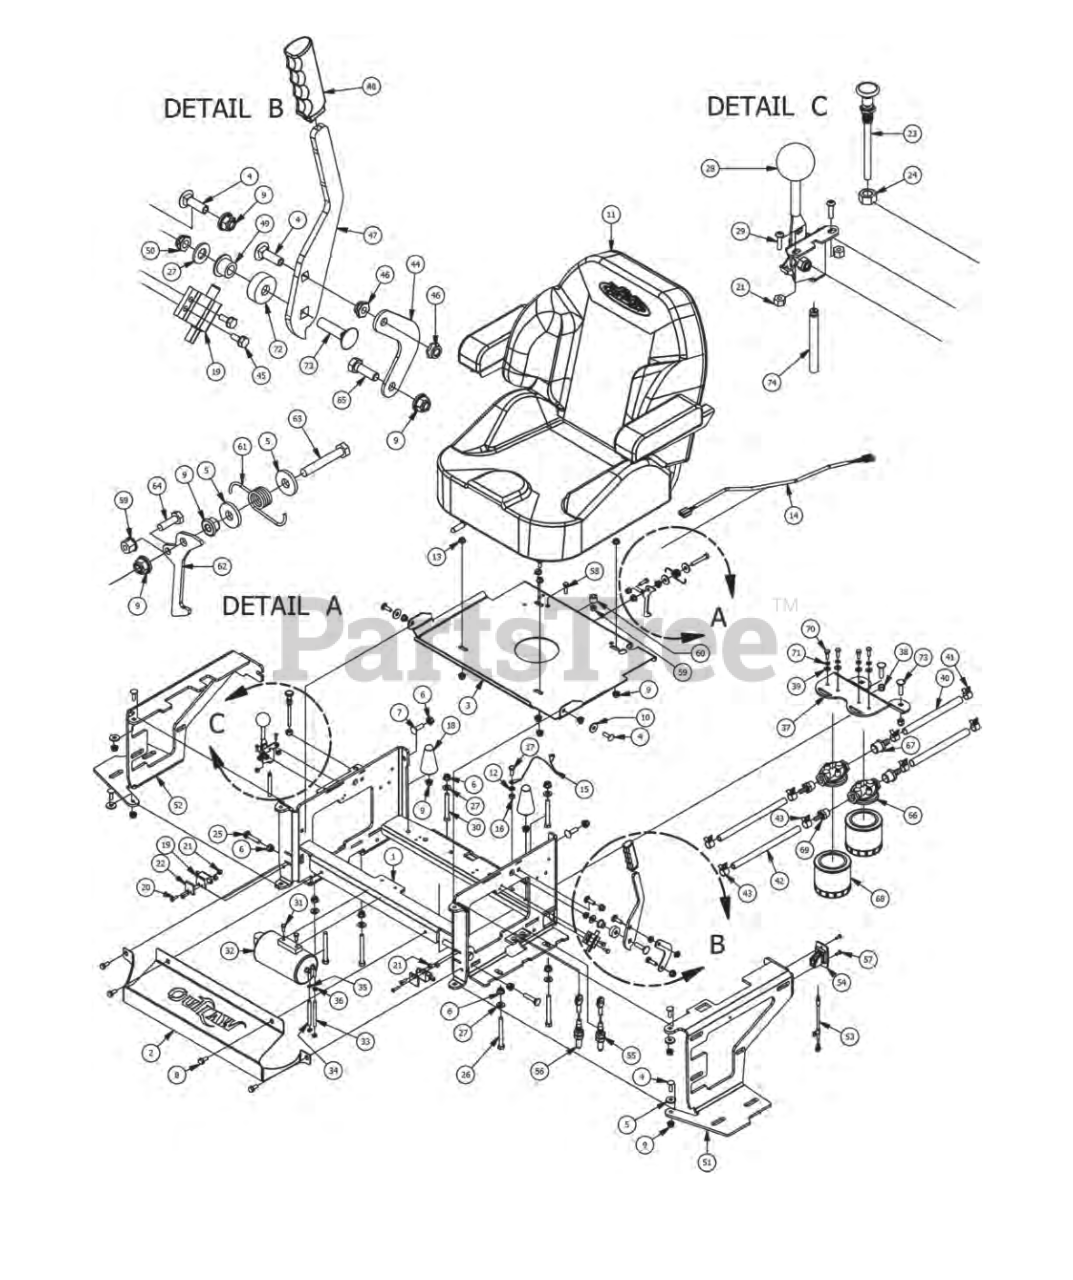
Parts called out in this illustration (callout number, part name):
1	2015 Outlaw Seat Bracket
2	Oudaw Cooler Cover
3	Seat Plate
4	5/16" 1 Carriage Balt
5	360 ID Plastic Washer
6	3/8" Nylock Flange Nut
7	3/8" x 1 1/4" Carriage Bolt
8	5/16 x 3/4 washer head type F screw
9	5/16 Flange Nut Zinc W/Serrations
10	360 10 Plastic Washer-Black
11	2015 Outlaw Seat
12	5/16" Lock Washer
13	5/16" Flange Nut
14	Seat Switch Adapter
15	Seat Cable
17	5/16" x 3/4" Hex Bolt
18	Rubber Cone-1621-153
19	Safety Switch
20	10-24 x 1 BS C/S 18-8 SS
21	10-24 Nylon Insert Locknut
22	Switch Block Plastic
24	3/8 readed Jam Nut
25	3/8 x 1 3/4 Carriage Bolt
26	3/8-16x3-1/2 grade 5 hex bolt
27	3/8" Flat Washer
28	Universal Throttle Head-2012
29	10-24 X 5/6 BS C/S 16-8 SS
30	3/8-16x3 grade 5 hex bolt
31	M6-1.0 X 16MM Hex Bolt
32	Carbon Canister ZT,CZT,Outlaw
33	1/4" vinyl tubing
34	3/16 vinyl tubing
35	3/16" Vinyl Hose Clamp
36	3/16 vinyl clamp
37	Outlaw Filter Bracket
38	3/8 Nylock Nut
39	1/4" Flat Washer
40	1/2 Clear Braded Hose Priced/Foot
41	1/2 Hose Clamp
42	3/8 clear hose
43	3/8 hose clamp
44	Brake Cable Adapter Bracket
45	12-24x 1/2 HWH Bolt
46	5/16-18 Nylock Jam Nut 1/2 Nut
47	Brake Handle Cam Over-
48	Rubber Brake Grip-cZT/ZT 2013
49	Bronze Bushing SF-1220-8
50	3/8-16 Hex Flange Top L/N
51	Outlaw 2015 Tank Support (Left)
52	Outlaw 2015 Tank Support (Right)
53	2015 Seat Latch Cable
54	2015 Seat Latch Toggle
55	2015 XP Brake Cable-Long
56	2015 XP Brake Cable-Short
57	3/16 Rivet
58	1/4-20 w1 GR 5 hex bolt zinc
59	1/4-20 Nylon Insert flange Nut
60	380x.735x.470 Nylon Space
61	Torsion Spring for Seat latch
62	Seat Latch Lever
63	5/16-18 X 2 Hex C/S (GR.5) ZC
64	1/4-20 x 1-1/4 GR 5 Hex Bolt
65	5/16 x 1" Bolt
66	Filter Head-Hydraulic Filter
67	Filter Head Fitting 1/2 x 1/2
68	Hydraulic filter
69	1/2" Pipe to 3/0 Barb
70	1/4" x 3/4" Hex Bolt
71	1/4 Lock Washer
72	2015 Brake Lever Spacer
73	3/8 1 1/2 Carriage Bolt
74	Outlaw Throttle Cable (Cable Only)
